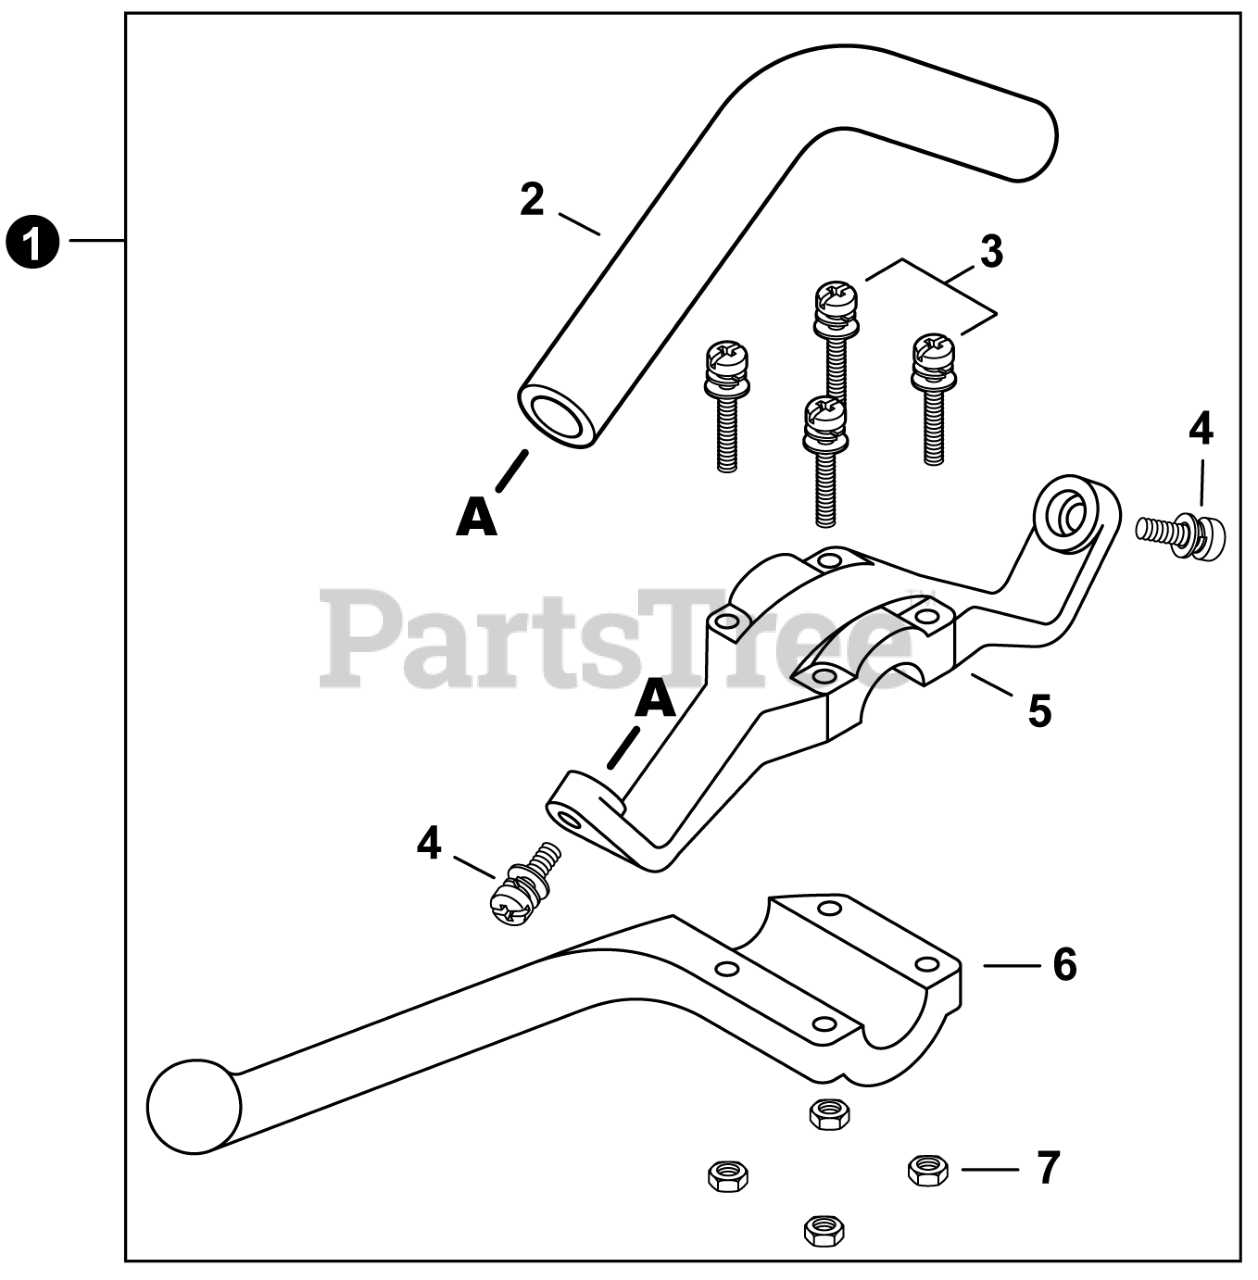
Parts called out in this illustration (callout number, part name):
1	HANDLE ASSY - LOOP
2	HANDLE, LOOP
3	SCREW 5x35
4	SCREW 5x14
5	BRACKET, HANDLE
6	BAR, BARRIER
